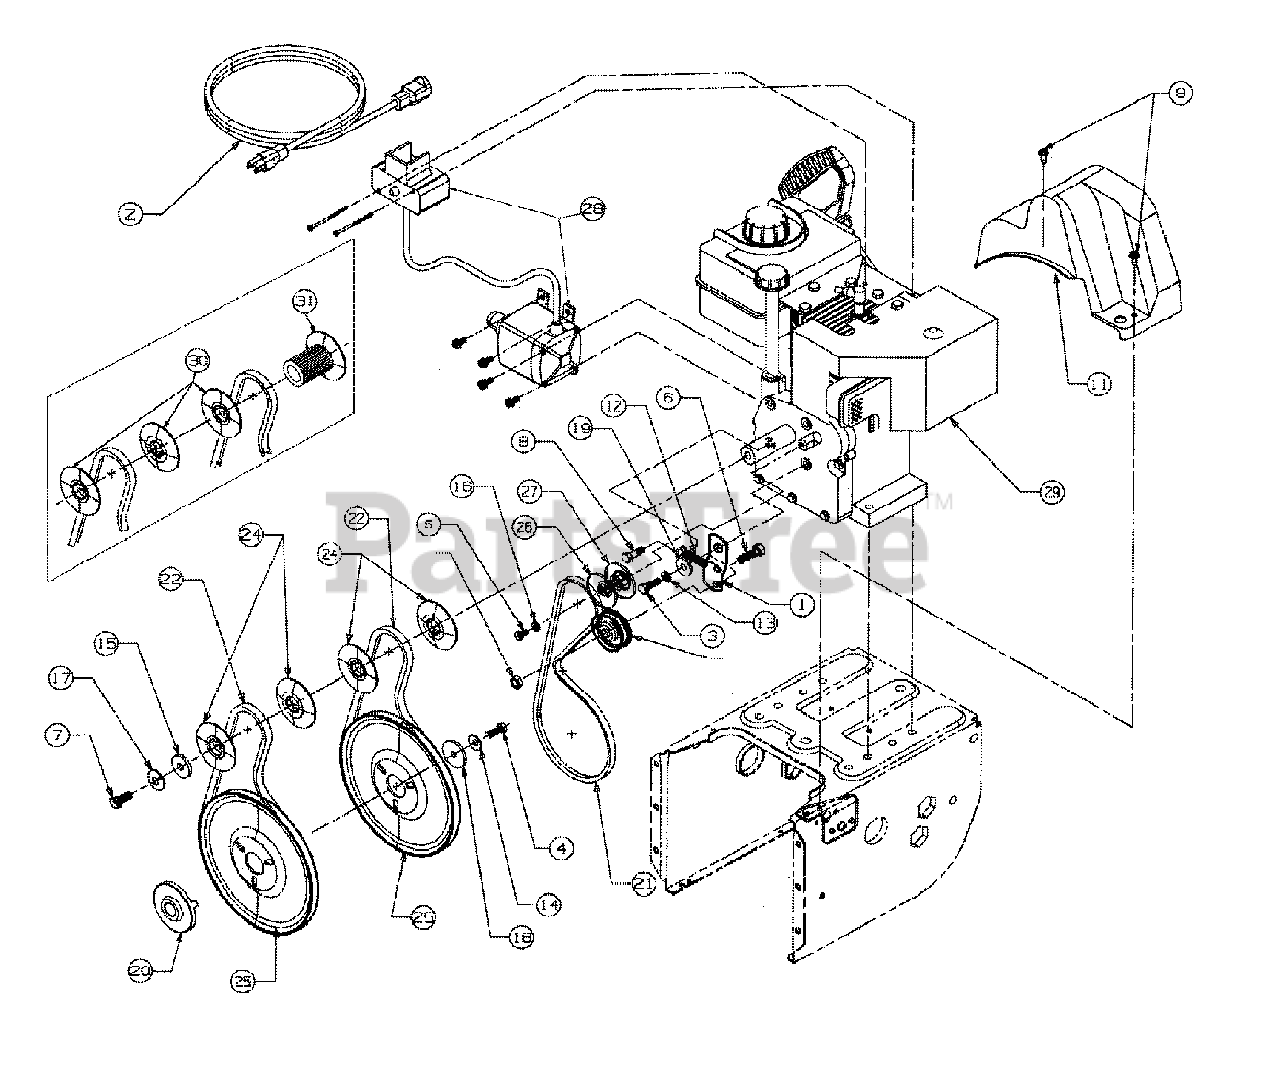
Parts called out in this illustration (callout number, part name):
3	Screw
4	Screw
5	Screw
6	Screw
7	Screw
8	Screw
9	Screw
10	Nut, Hex
11	Belt Cover
12	Spring
13	Washer-Flat
14	Washer-Bell
15	Washer-Flat
16	Washer-Lock
17	Washer-Bell
18	Washer-Flat
19	Shoulder Spacer
20	Pulley, Adapter
21	V-Belt
22	V-Belt Matched
24	Pulley, Half
25	Pulley-Auger
26	Pulley Half
27	Pulley Half
28	Starter
29	Engine
30	Pulley, Half
31	Pulley, Half
